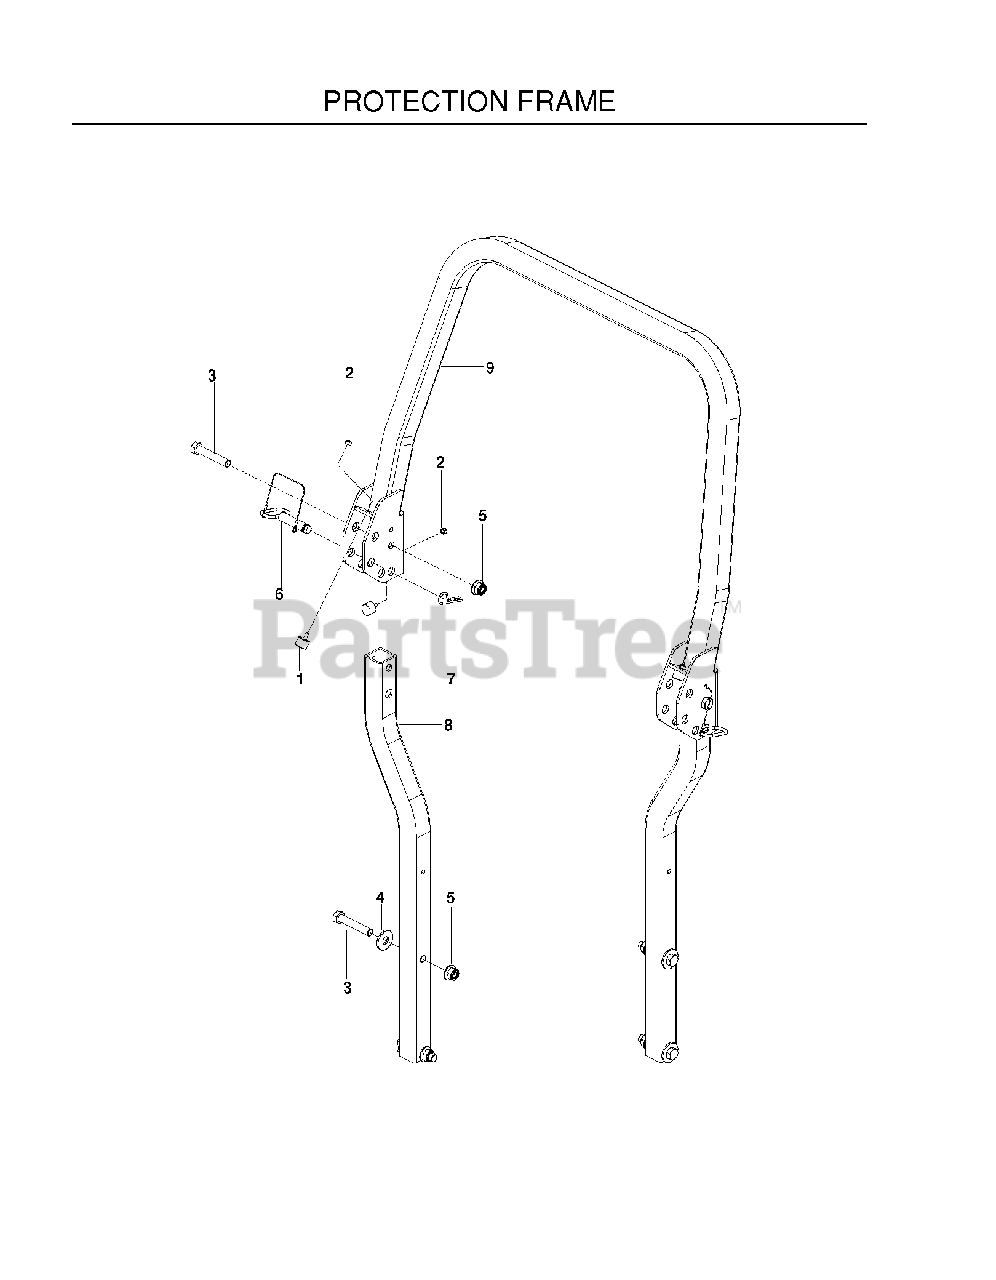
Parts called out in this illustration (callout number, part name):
1	BUMPER, MALE STUD, 1/4-20
2	RP_NUT 1/4-20 NYLOC
3	5/8-11 X 3-1/2 HHB GRADE 5
4	WASHER, 5/8 FLAT
5	NUT 5/8-11 FLG NYLOC ZD
7	PIN HAIR .148 X 2-15/16 #210
8	TUBE.SIDE.ROPS.GREY
9	ROPS.TOP.GRAY
